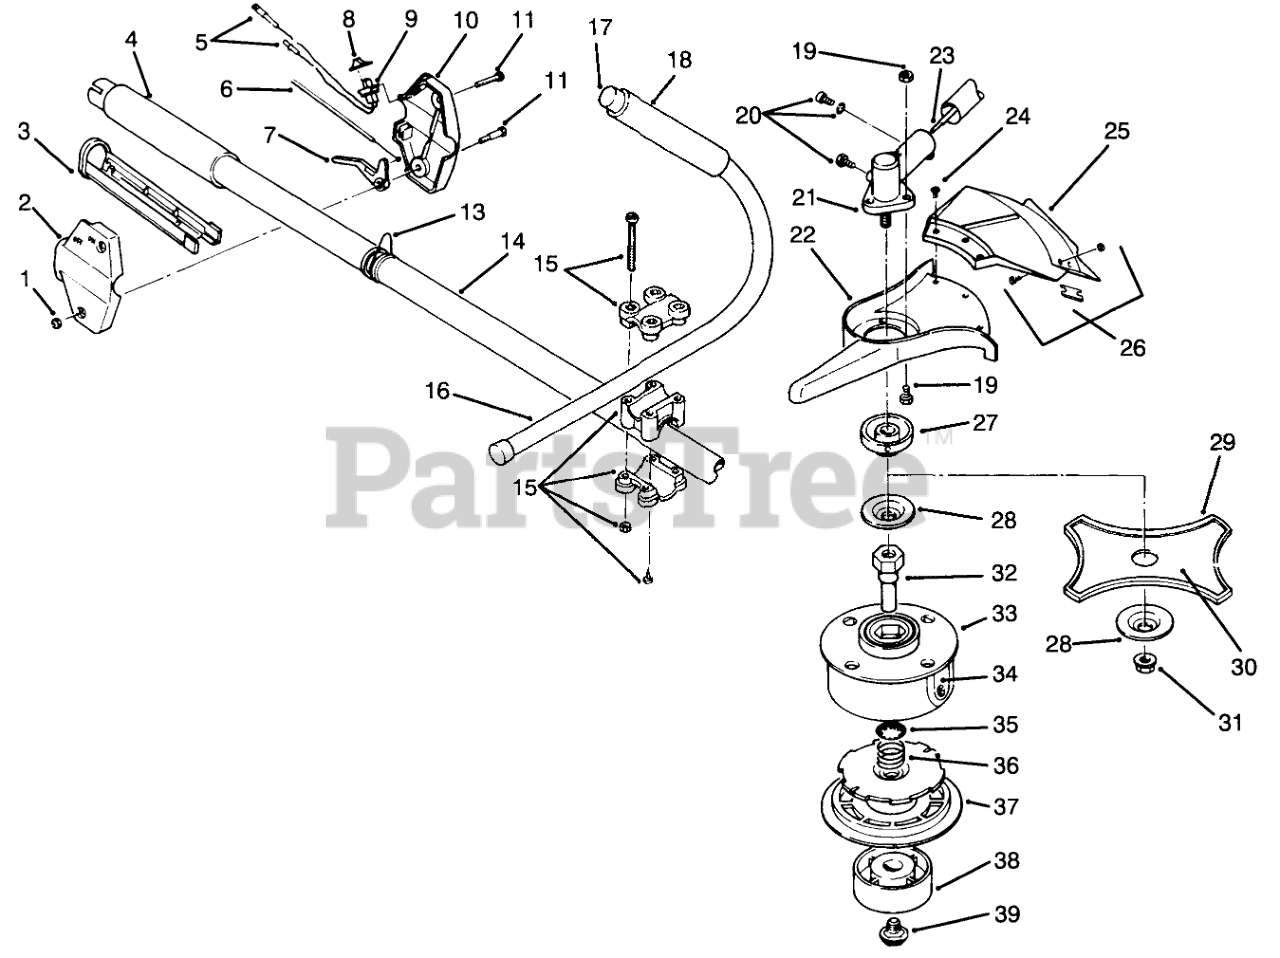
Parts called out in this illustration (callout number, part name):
1	NUT-LOCK, NI
2	HOUSING RH
3	TROUGH 1"
4	GRIP - RUBBER
5	LEAD WIRE ASM
6	THROTTLE CABLE
7	THROTTLE LEVER
8	SWITCH COVER
9	SWITCH
10	HOUSING LH
13	Clip-Shoulder Strap
14	DRIVE SHAFT HSG ASM
15	Assy.-Bracket, Handle (Incl. 4 Screws & 4 Nuts)
16	Assy.-J-Handle (Incl. Ref. No.17 & 18)
17	TUBE CLOSURE
18	HANDLE NITRILE GRIP
19	SCREW
20	MTG HDW&PLUG SET
21	Assembly-Gear Box (Incl. Ref. No. 27 & 28)
22	GUARD MOUNT
23	FLEXIBLE DRIVE SHAFT
24	GUARD MNTG SCREW ASM
25	Assy.-Guard & Blade (Incl. Ref. #26)
26	Assembly-Blade (Incl. 2 Screws & 2 Nuts)
27	Driver-Blade
28	Blade Retaining Washer
29	BLADE SAFETY GUARD
30	Blade (Incl. Ref. No.29)
31	BLADE RETAINER NUT
32	SPOOL SHAFT
33	Outer Spool & Eyelet Asm.
34	EYELET
35	RETAINER ( 10 PACK)
36	SPRING
37	INNER REEL
38	Assy.-Bump Head
39	Bolt-Bump Head
